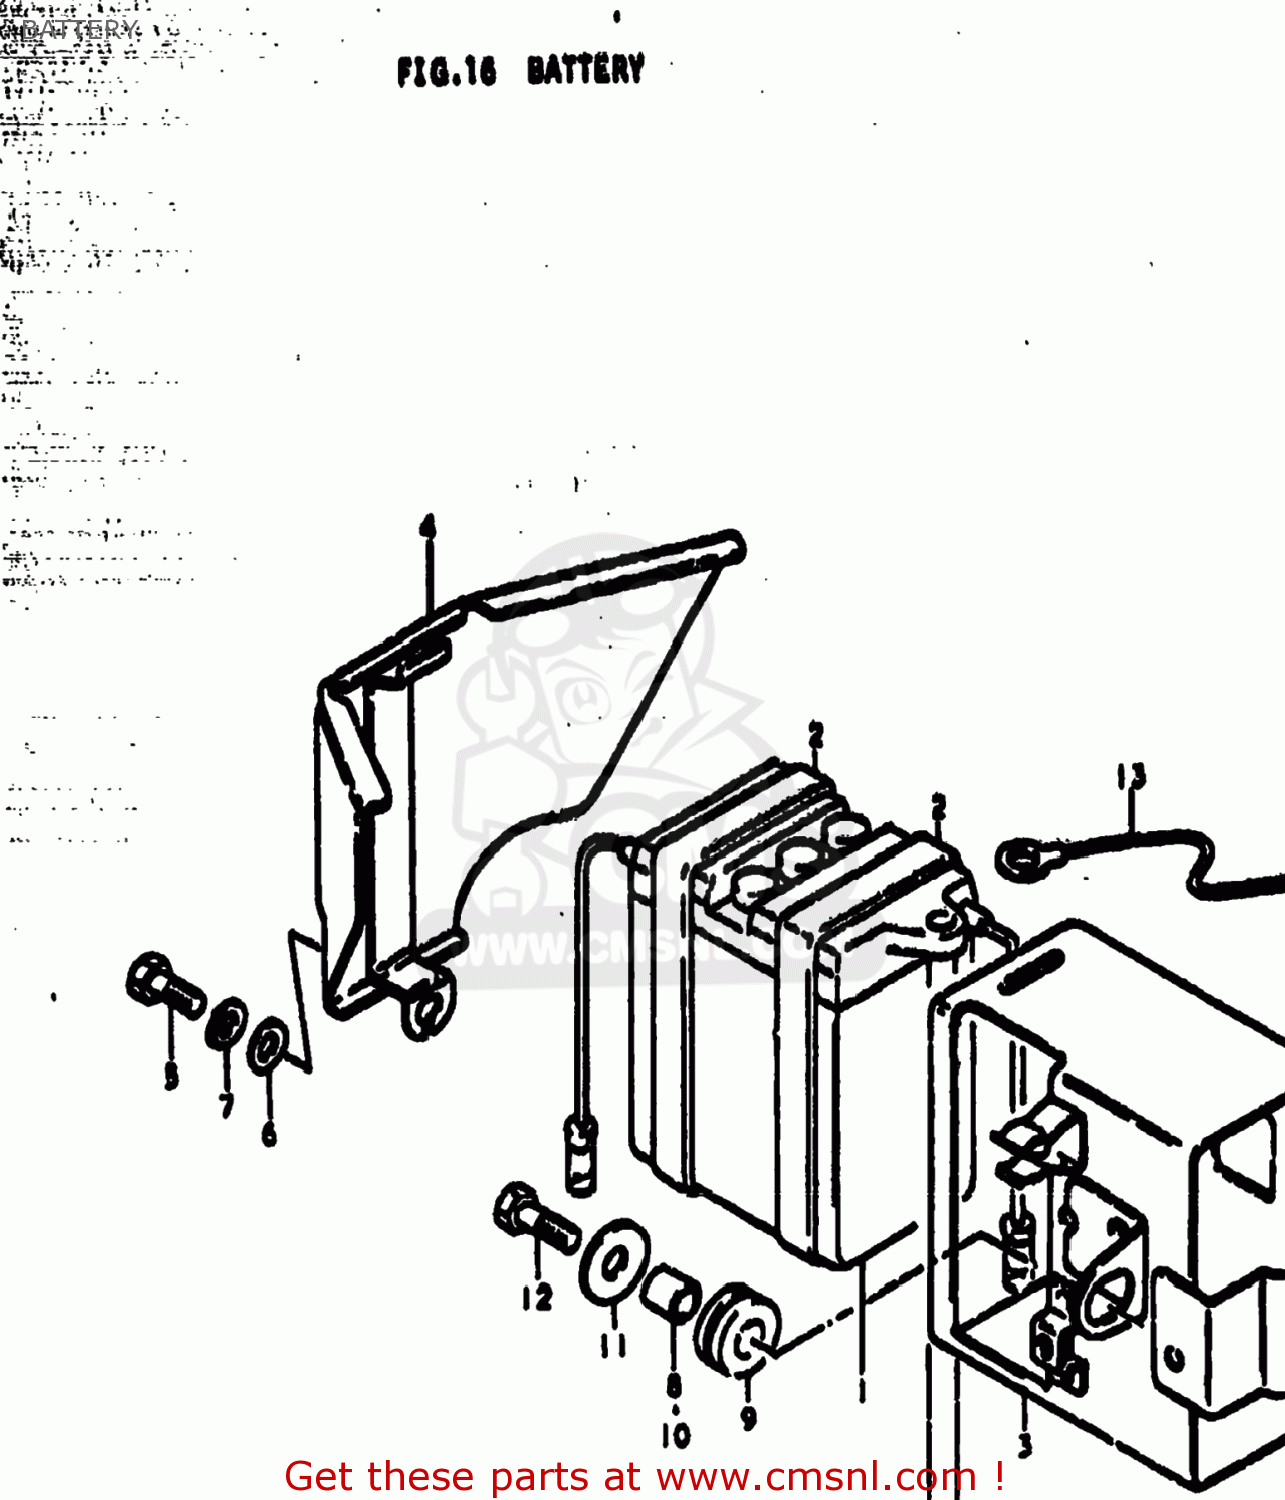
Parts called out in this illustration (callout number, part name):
1	BATTERY(6N4B-2A,6V4.2AH)
2	PROTECTOR,BATTERY
3	HOLDER,BATTERY
4	COVER,BATTERY HOLDER
5	SCREW(6X10)
6	WASHER
7	LOCK WASHER
8	SPACER (6.3X9.1X6.7)
9	CUSHION
10	SPACER (7X9X7)
11	WASHER (6.5X20X1.2)
12	SCREW
13	LEAD WIRE
